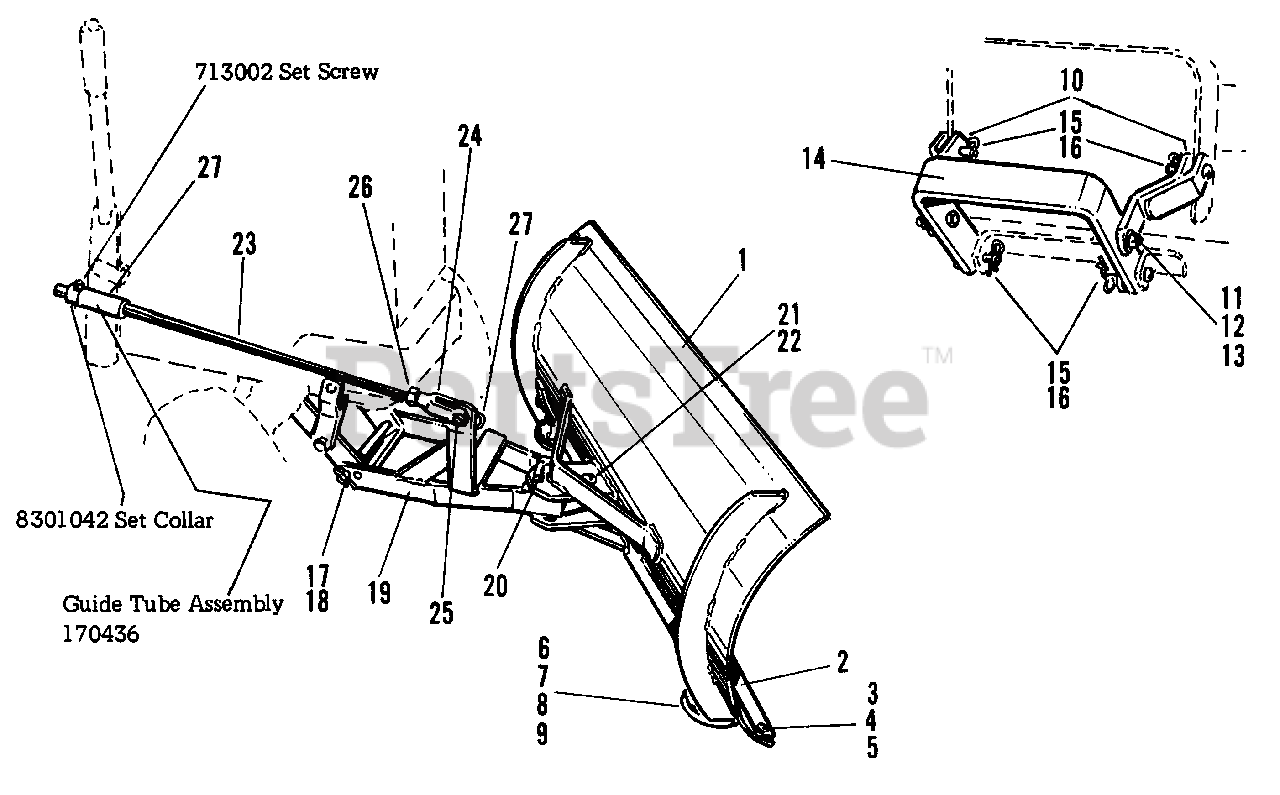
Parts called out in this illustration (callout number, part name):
1	42" Blade Assembly
2	Wear Plate
3	Carriage Bolt, 3/8"-16 x 3/4" lg.
4	Lock Washer, 3/8"
5	Hex Nut, Full, 3/8"-16
6	Shoe Assembly
7	Carriage Bolt, 3/8"-16 x 1" lg.
8	Lock Washer, 3/8"
9	Hex Nut, Full, 3/8"-16
10	Support Arm Assembly
11	Hex Capscrew, 3/8"-16 x 1" lg.
12	Lock Washer, 3/8"
13	Hex Nut, Full, 3/8"-16
14	Push Frame
15	Pin
16	Spring Clip
17	Pivot Rod
18	Spring Clip
19	Push Bar Assembly
22	Spring Clip
24	Adjusting Yoke End
26	Hex Nut, Full, 1/2"-20
27	Spring Clip
